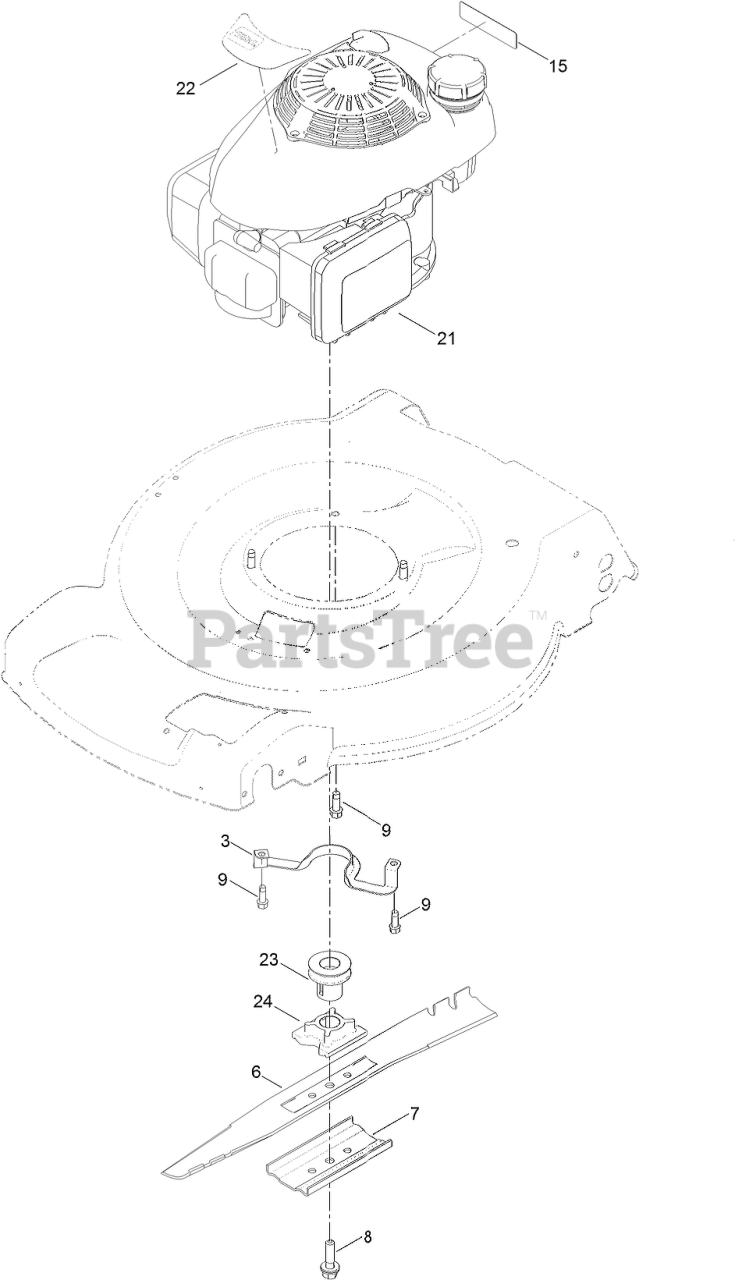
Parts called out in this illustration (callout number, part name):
3	GUIDE-BELT
6	BLADE-22 INCH
7	SUPPORT-BLADE
8	BOLT-BLADE
9	SCREW-TAPTITE
15	DECAL-ARRESTER, SPARK
22	DECAL-SHROUD, HONDA
23	PULLEY
24	RETAINER-BLADE
